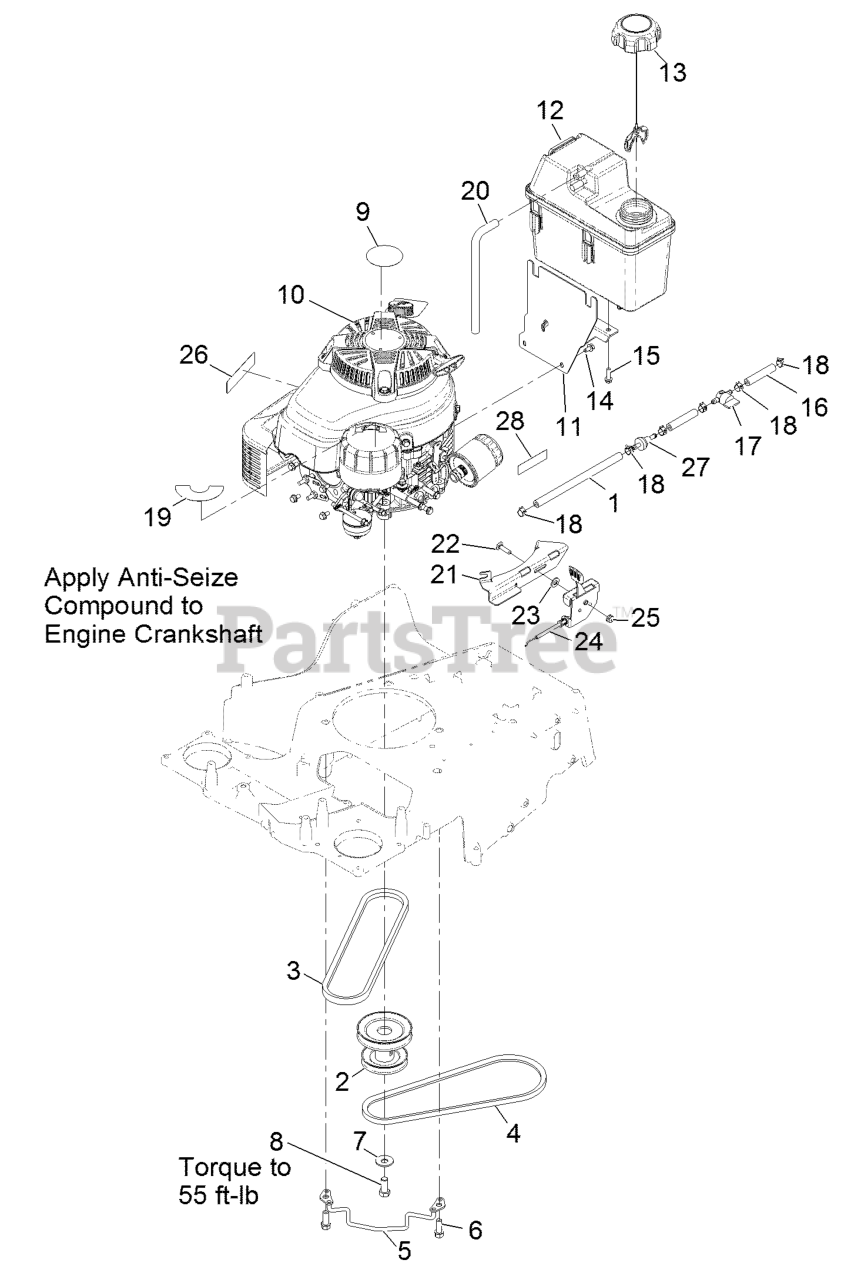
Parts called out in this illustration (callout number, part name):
1	HOSE-FUEL
2	PULLEY-ENGINE
4	BELT
6	SCREW-TAPTITE
7	WASHER-BELLEVILLE
8	SCREW-HH
11	MOUNT-TANK
14	SCREW-HWH
15	SCREW-HWH
16	HOSE-FUEL
17	VALVE-FUEL
18	CLAMP-HOSE
20	HOSE-VENT, CANISTER
21	BRACKET-MOUNT, THROTTLE
22	SCREW-CARR
23	WASHER-PLAIN
24	THROTTLE
26	DECAL-ARRESTER, SPARK
27	FILTER-FUEL
28	DECAL-WARNING, ENGINE
